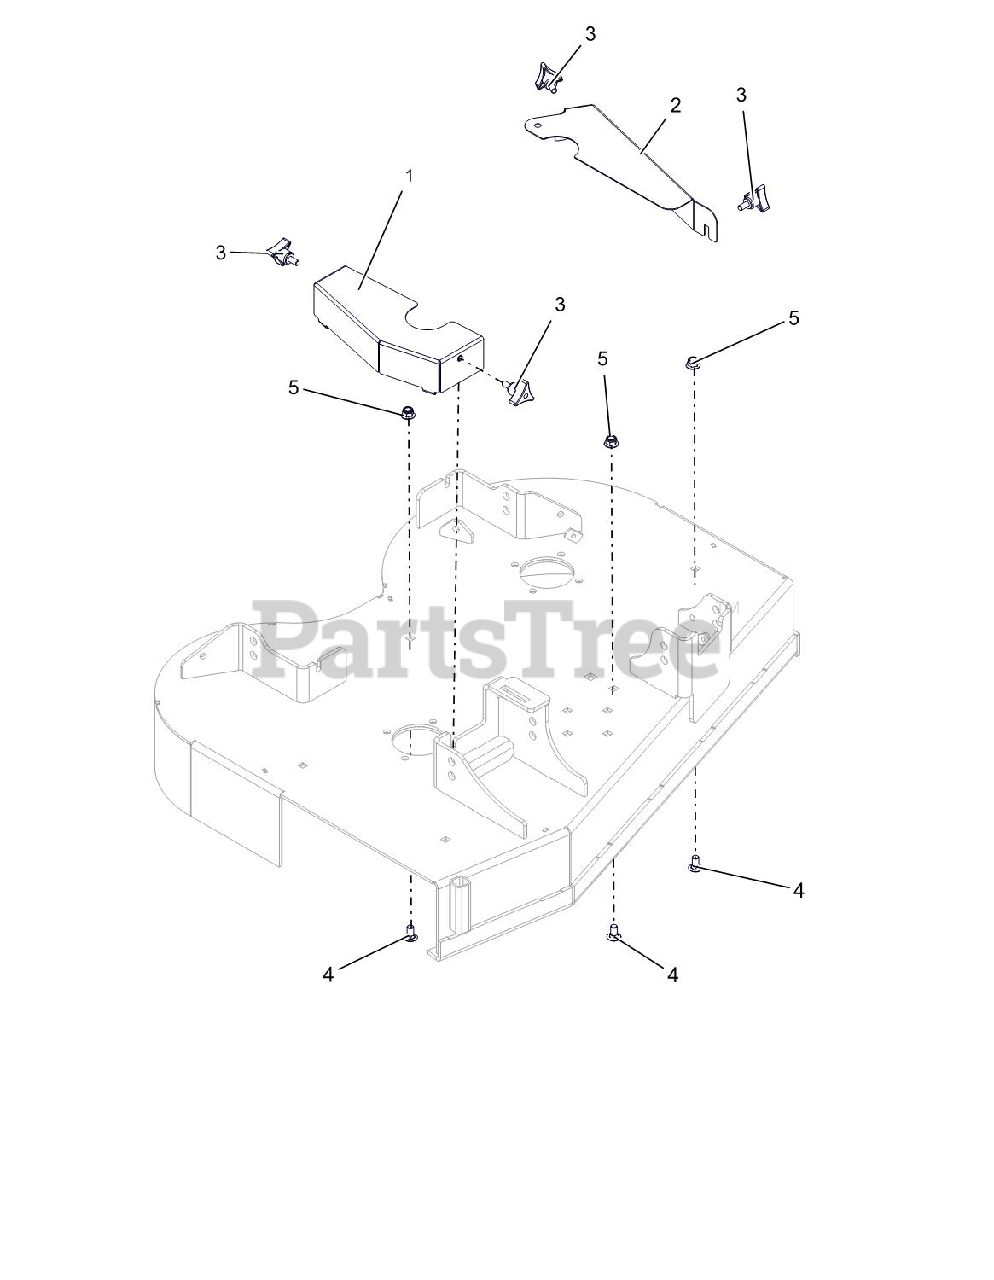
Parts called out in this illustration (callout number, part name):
1	GUARD, RH SPINDLE
2	GUARD, LH SPINDLE
3	KNOB,WING STUD 5/16-18 X .75
4	@BLT-RDHDSQNK .38-16X.75 G5YZ
5	@NUT-LK-NYL-FLG .38-16 YWZC
